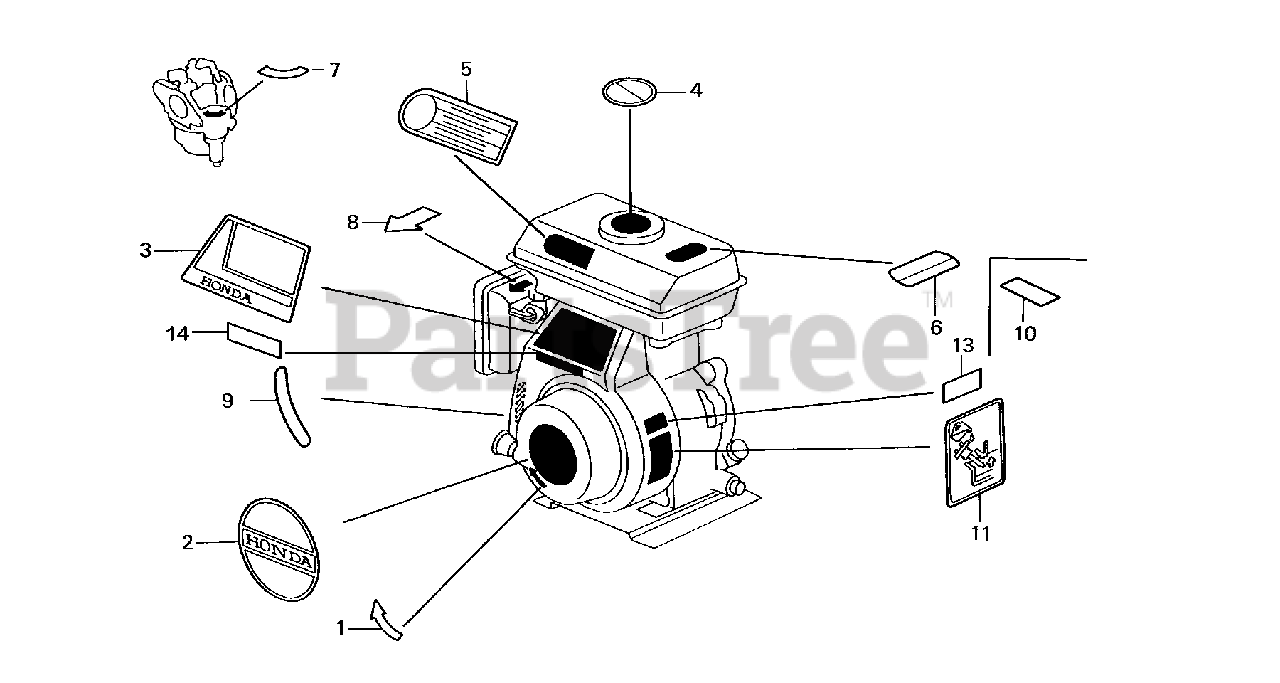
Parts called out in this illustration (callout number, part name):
1	MARK, STARTING
3	EMBLEM (ENGLISH/FRENCH/SPANISH)
5	MARK, CAUTION (ENGLISH/FRENCH)(SPANISH)
6	MARK, CAUTION (ENGLISH/FRENCH)(SPANISH)
8	MARK, CHOKE
9	MARK, THROTTLE
11	MARK, OIL CAUTION
